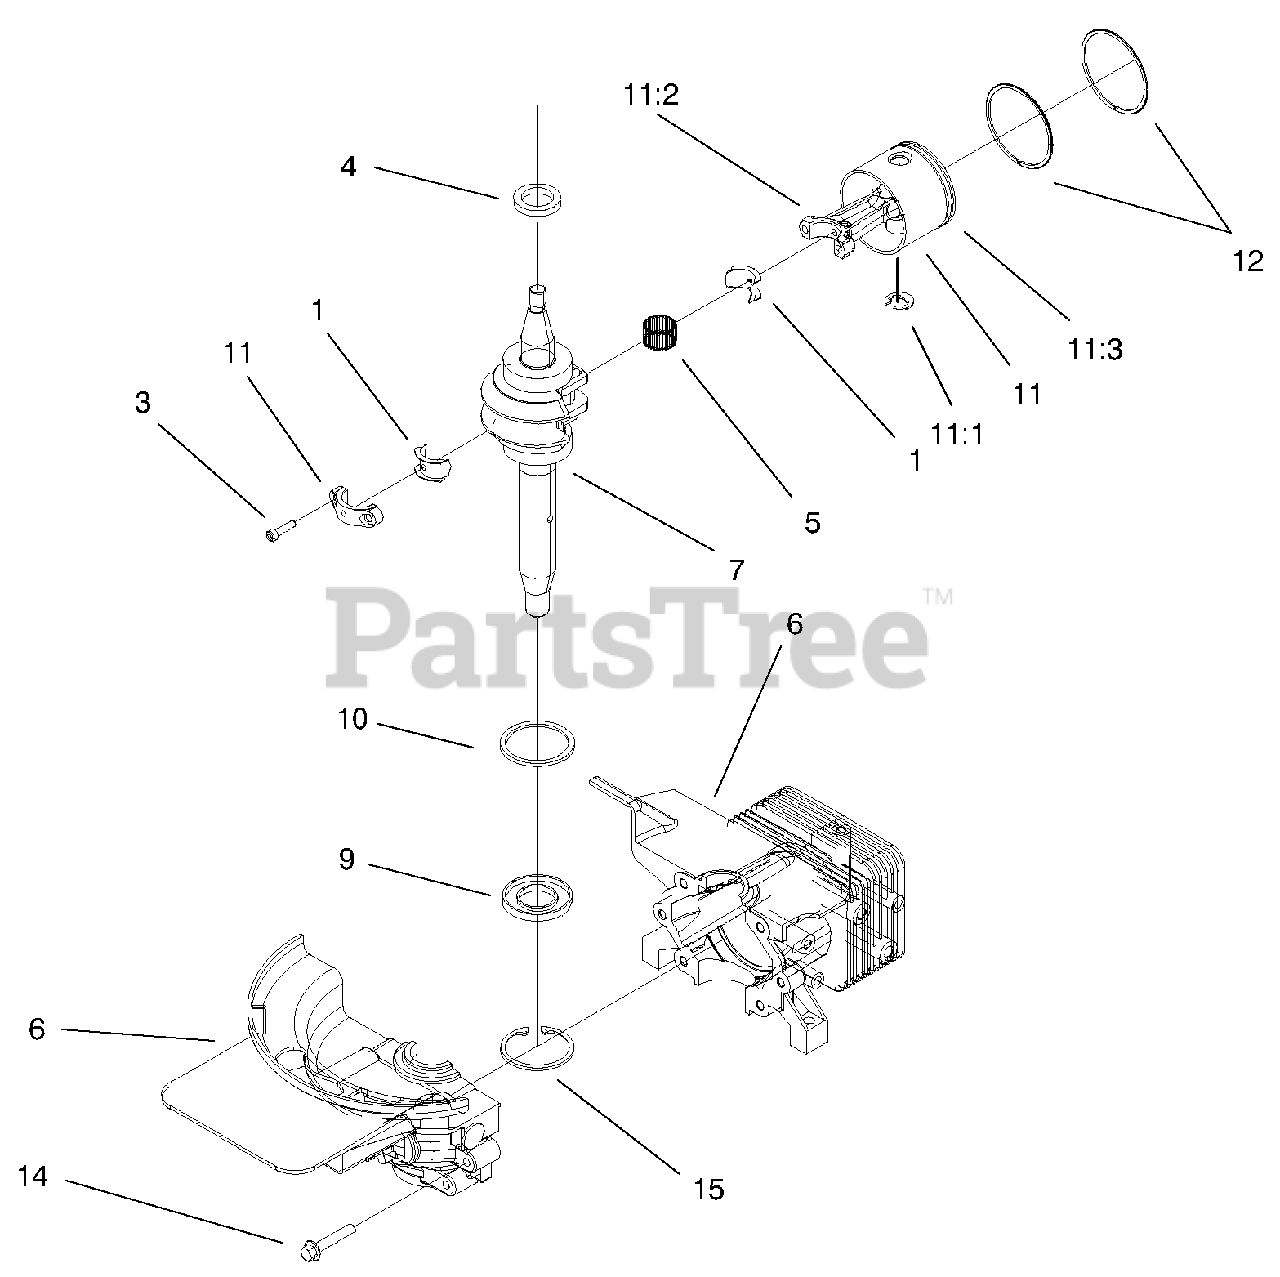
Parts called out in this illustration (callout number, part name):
1	Liner ASM
2	Sealant-50cc #2
2	Sealer-Loctite
3	Screw-Rod
4	Seal-Oil
5	Bearing-Needle
6	Cylinder And Crankcase ASM
7	Crankshaft And Bearing ASM
9	Seal-Oil
10	Ring-Retaining
11	Piston & Rod ASM
11:1	Ring-Retaining
11:2	Connecting Rod ASM
11:3	Piston ASM With Piston Rings
12	Ring Set
15	Ring-Retaining
